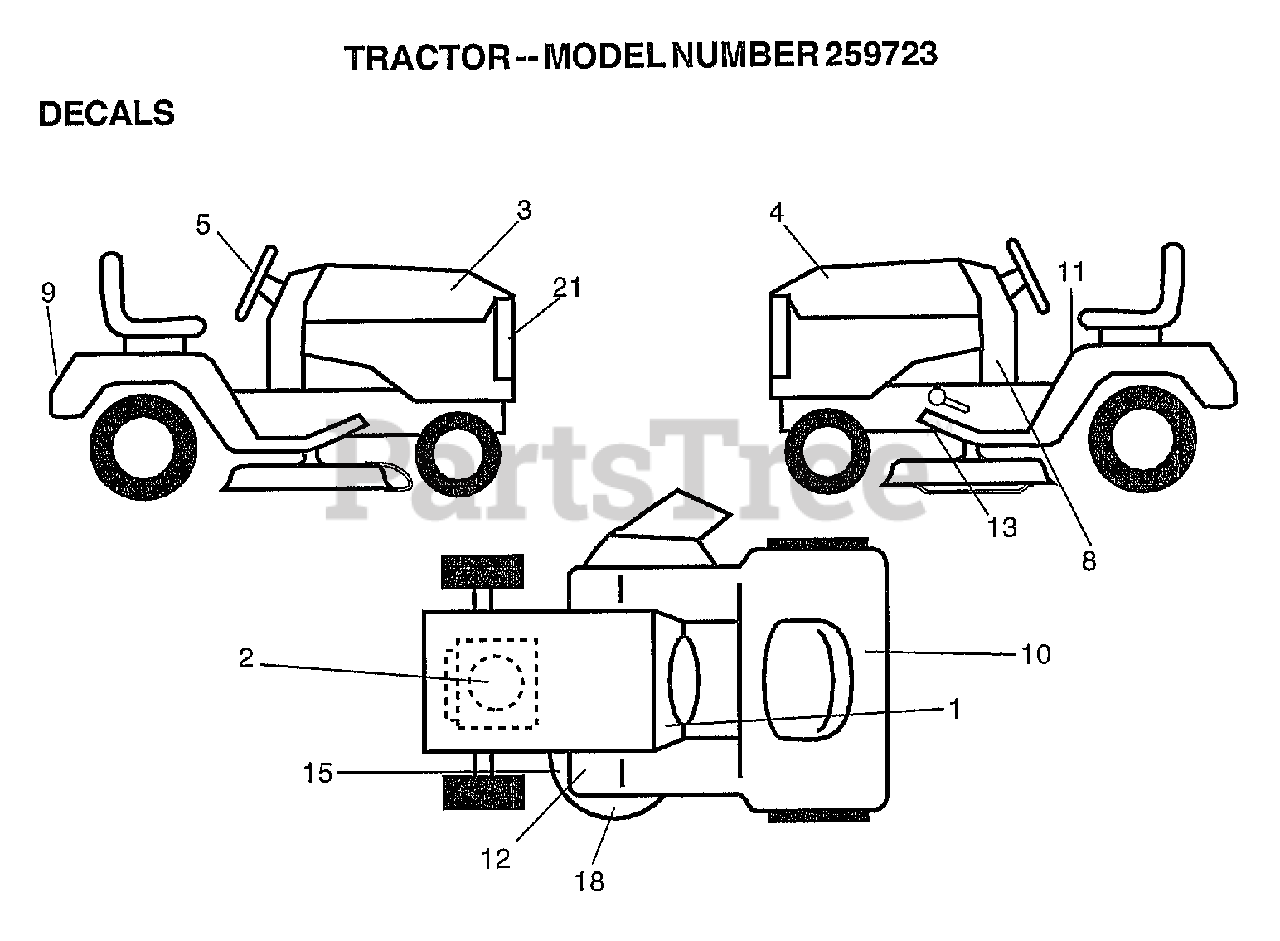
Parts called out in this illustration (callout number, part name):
1	"DECAL DASH,OPER."
2	DECAL HP ENGINE
3	DEECAL.HOOD.RH
4	DECAL.HOOD.LH
5	DECAL, INS STRG WH
8	DECAL.PNL.SD
9	DECAL, FENDER
10	DECAL.BATRY.3-3908
11	"DECAL-FENDER,DANG"
15	DECAL
18	DECAL.MOWER.HOME
21	DECAL, GRILLE LENS
